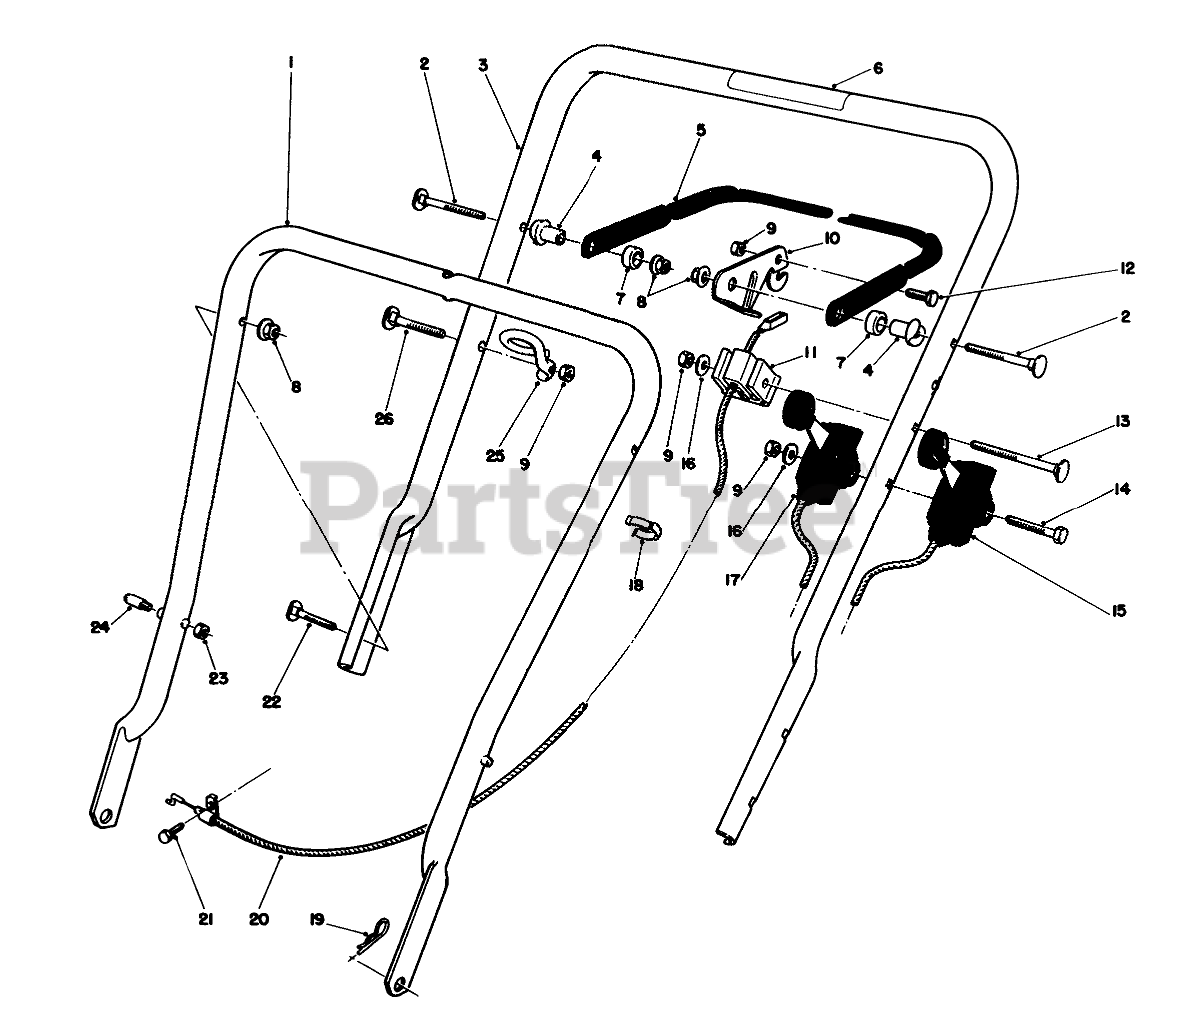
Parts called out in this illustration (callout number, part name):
1	LOWER HANDLE ASM
2	5/16-18 X 2 HNDLE SCREW
3	Handle-Upper (Incl. Ref. #6)
4	SPACER-SUPPORT
5	Bar-Control
6	Decal-Danger
7	SPACER-NYLON
8	NUT-LOCK, NI
9	NUT-LOCK, NI
10	Lever-Control
11	SUPPORT-CABLE
12	SCREW-HH
13	HANDLE SCREW
14	SCREW-HH
15	Control-Traction (Bend Type #3)(Sheath Lg. 46")(WireLg. 1-1/4")
16	WASHER-FLAT
17	SERVICE THROTTLE CONTRO
18	BOWDEN CLIP
19	PIN-COTTER, HAIR
20	BRAKE CABLE
21	SCREW-HH
22	SCREW
23	NUT-LOCK, NI
24	HANDLE PIN
25	Guide
26	HANDLE SCREW
